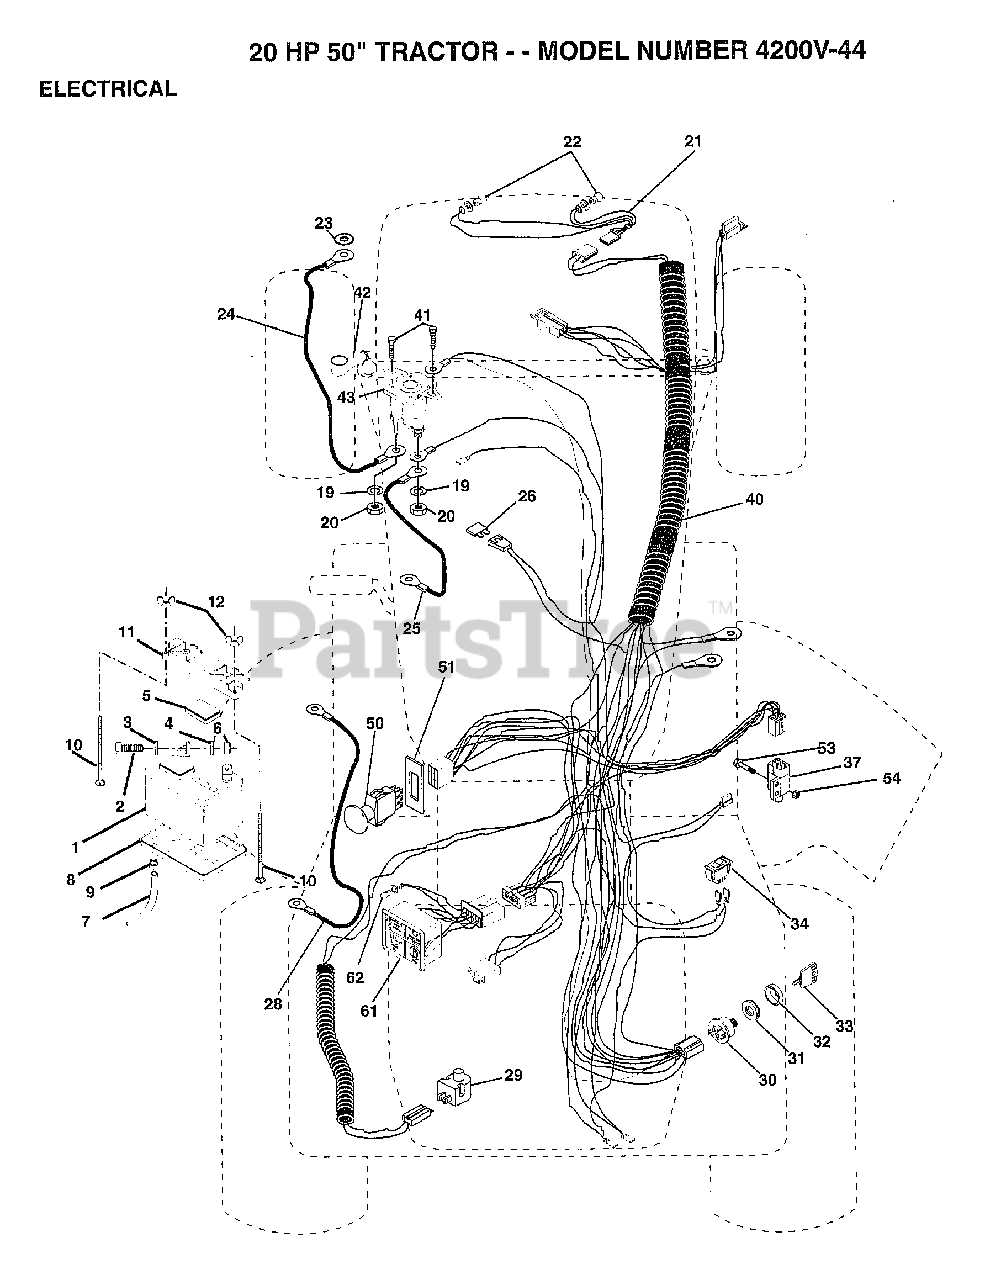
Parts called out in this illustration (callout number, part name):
2	BOLT LT
3	WASHER
4	LOCKWASHER
5	"CAP,BATTERY "
7	"DRAIN TU T, BATT"
8	"TRAY T, BATTERY"
9	HOSE CLAMP T
10	BOLT
20	NUT
22	HEADLAMP BULB
23	LOCKWASHER
24	CABLE-BATTERY T
25	CABLE-BATTERY T
26	FUSE HYT
28	CABLE T
29	SWITCH SEAT
32	COVER KEY SWITCH
33	KEY MLD GEN DELTA
34	SWITCH LT
37	SWITCH INTERLOCKT
40	HARNESS IGNITION
41	SCREW
51	RING RETAIN PTO
53	SCREW
54	"NUT,KEPS"
61	LIGHT.PKG.ASM.
62	BULB LIGHT T
70	HARNESS.ENG.VANII
